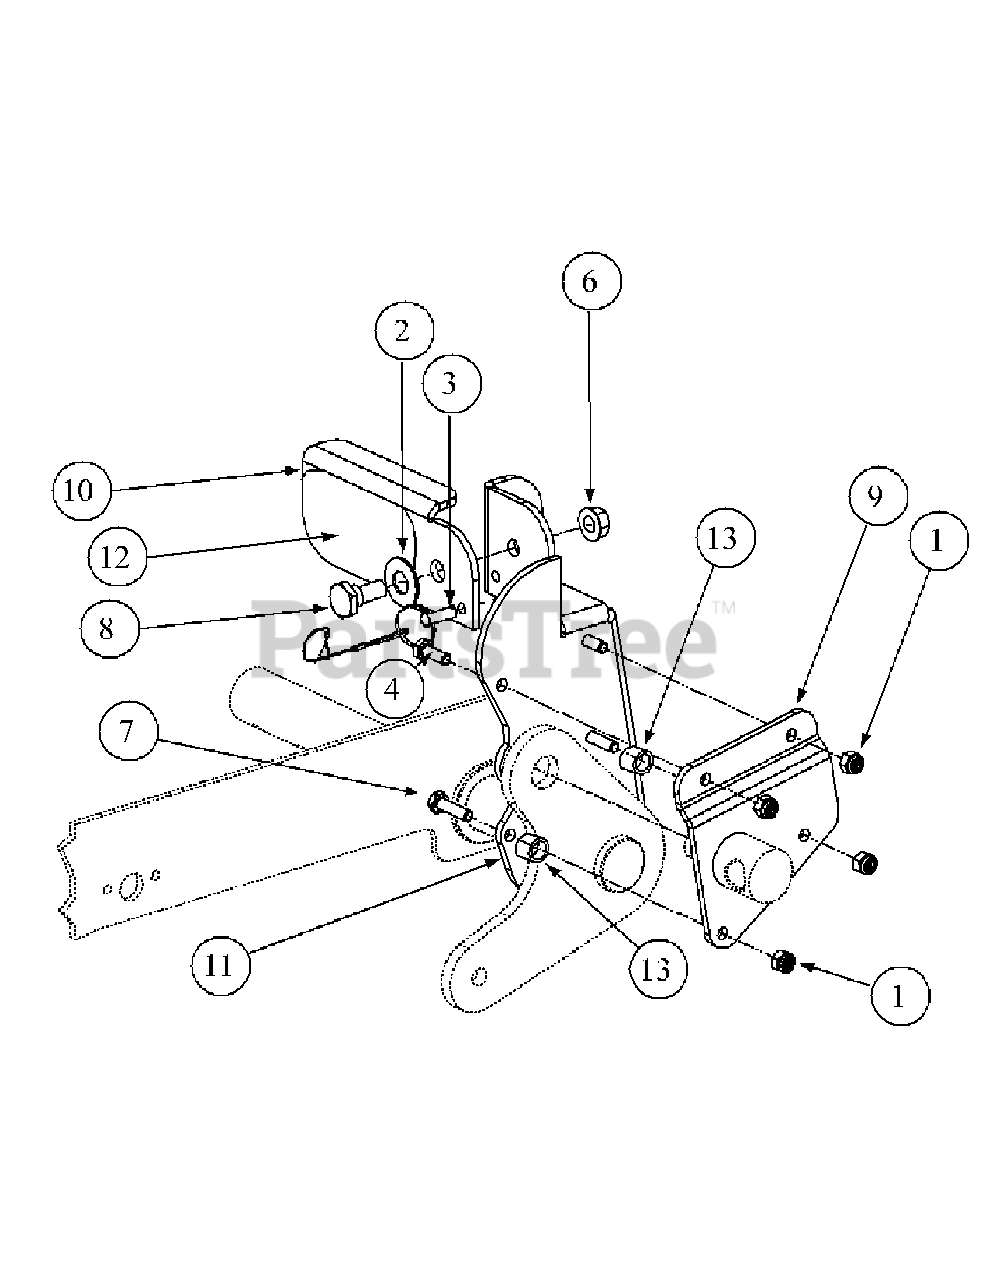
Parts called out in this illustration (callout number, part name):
1	Lock Nut, Nylon Insert, 1/4-20
2	Washer, 1/2 x 1 Shim
3	Detent Pin w/12" Lanyard
4	Hex Cap Screw, 1/4-20, .75
6	Hex Nut, Flange Lock 3/8-16
7	Hex Cap Screw, 1/4-20, 1.00
8	Shoulder Screw, .50 x .27 Lg., 3/8-16
9	Foot Lift Backup Pedal
10	Deck Foot Pedal Lift
11	Deck Foot Pedal Lift
12	Deck Foot Lift Pad
13	Turnbuckle Sleeve
